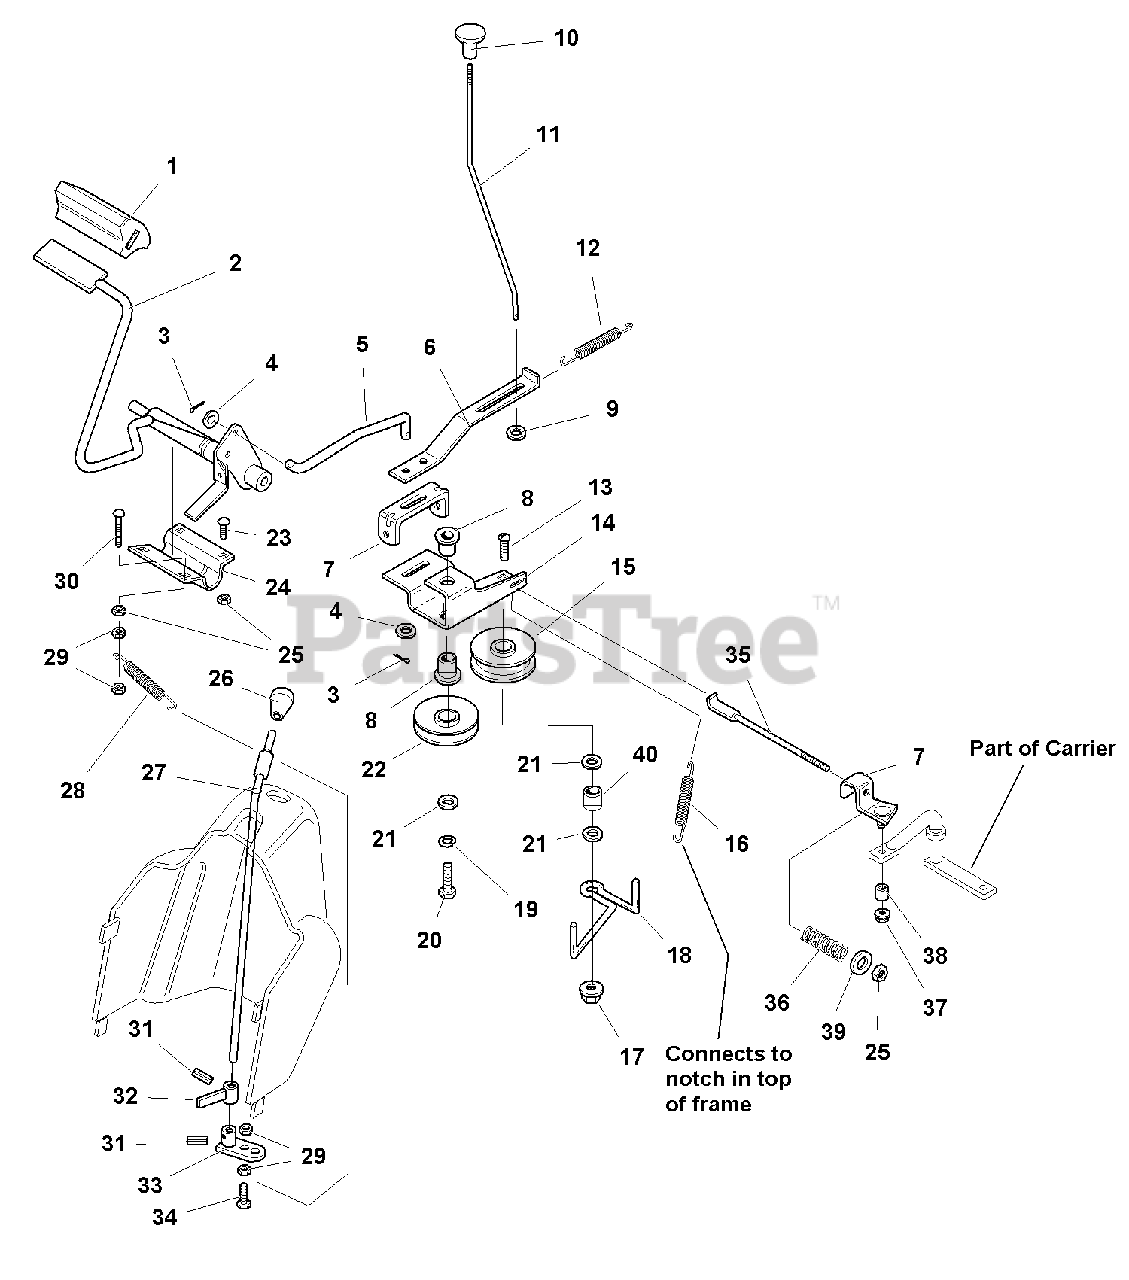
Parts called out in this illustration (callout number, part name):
1	PAD, Brake
2	FOOT PEDAL ASSEMBLY
3	PIN, Cotter, 1/8 x 3/4
4	WASHER, Plain, 5/16
5	ROD, Clutch
6	LEVER, Parking Brake
7	GUIDE, Brake Rod
8	BUSHING, Plastic, 5/8
9	WASHER, Plain, 1/4
10	KNOB, Plastic, Parking Brake
11	ROD, Parking Brake
12	SPRING, Parking Brake
13	CARRIAGE BOLT, 3/8-16 x 2-1/4
14	BRACKET, Idler
15	PULLEY, Backside
16	SPRING, Idler
17	NUT, Hex Flange Whiz Lock, 3/8-16
19	LOCKWASHER, 3/8
20	CAPSCREW, Hex Head, 3/8-16 x 1-3/4
21	WASHER, Plain, 3/8
22	PULLEY, Idler, V
23	CARRIAGE BOLT, 5/16-18 x 3/4
24	CLAMP, Tube
25	NUT, Hex Nylon Lock, 5/16-18
26	KNOB, Plastic, Gear Shift
27	SHAFT, PTO Clutch
28	SPRING, Extension
29	LOCKNUT, 5/16-18
30	CARRIAGE BOLT, 5/16-18 x 1 1/2
32	HUB & BAR ASSEMBLY, PTO Clutch
33	ARM & HUB ASSEMBLY, PTO Clutch
34	CAPSCREW, 5/16-18 x 1
37	NUT, Hex Flange Lock, 5/16-18
39	WASHER, 5/16 x 1
